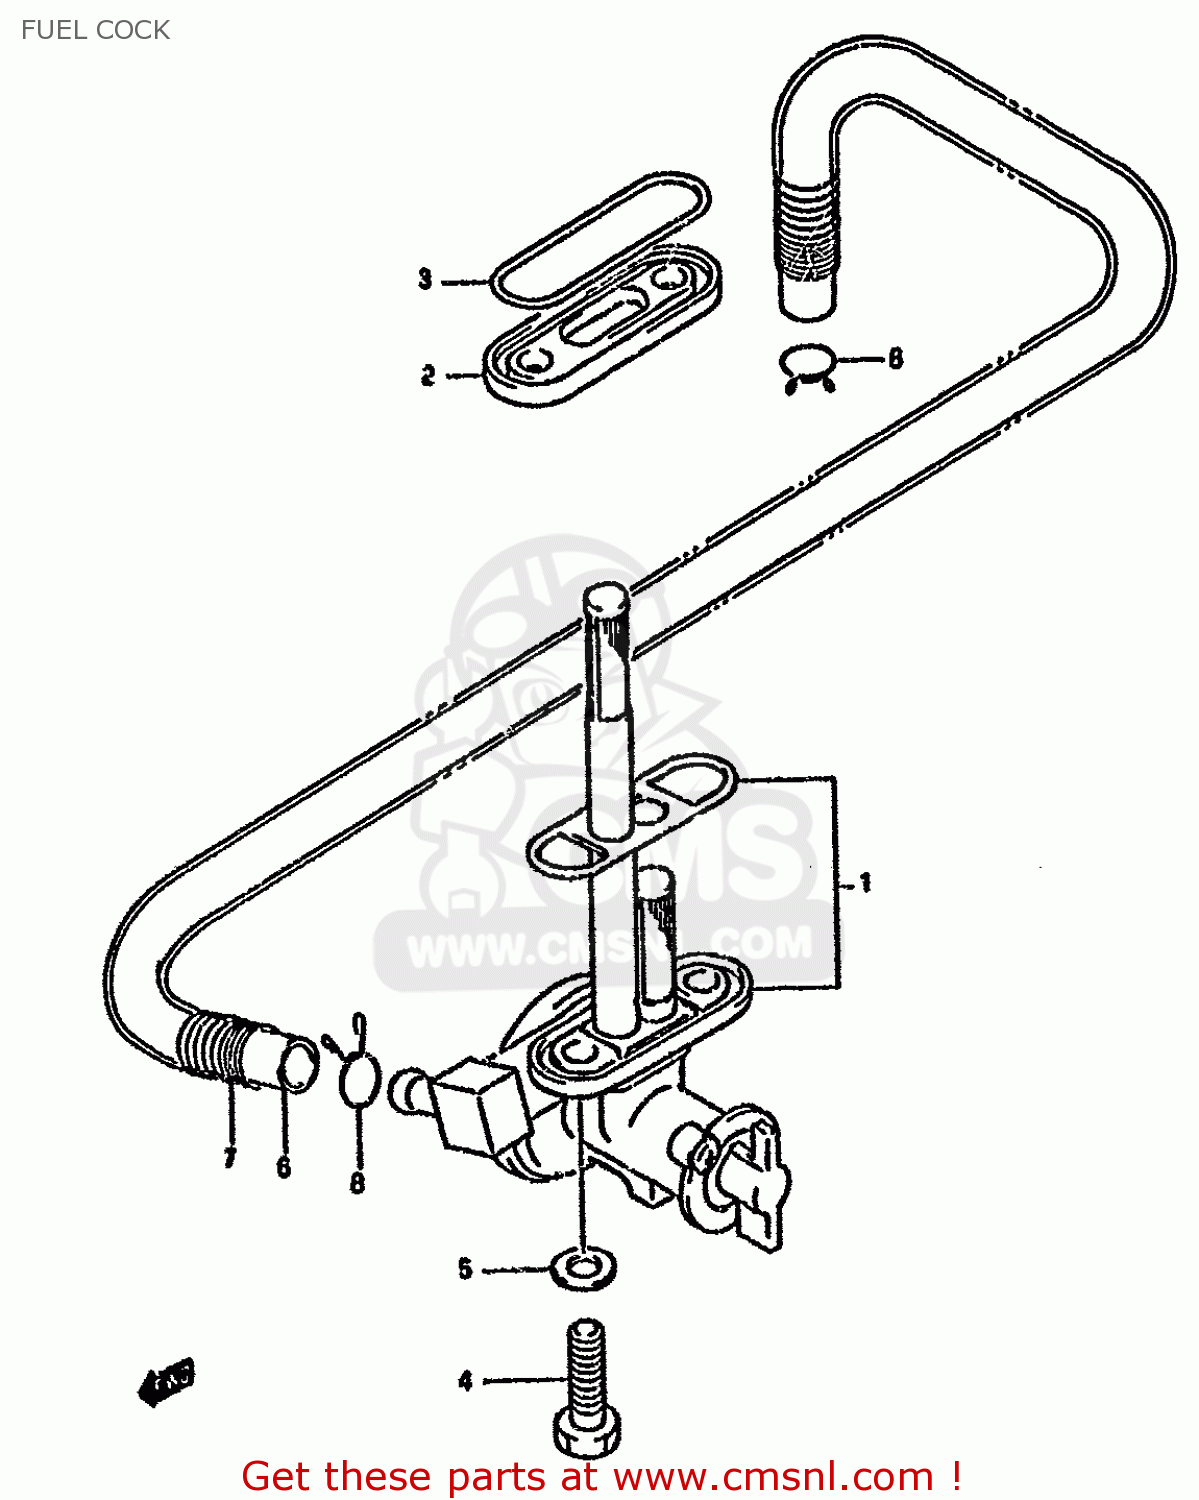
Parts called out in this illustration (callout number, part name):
1	COCK ASSY,FUEL
2	SPACER,FUEL COCK
3	GASKET,FUEL COCK (NAS)
4	SCREW (6X25)
5	GASKET(6.4X11.5X0.8) (NAS)
6	HOSE(7X10.2X600)
7	SPRING
8	CLIP
